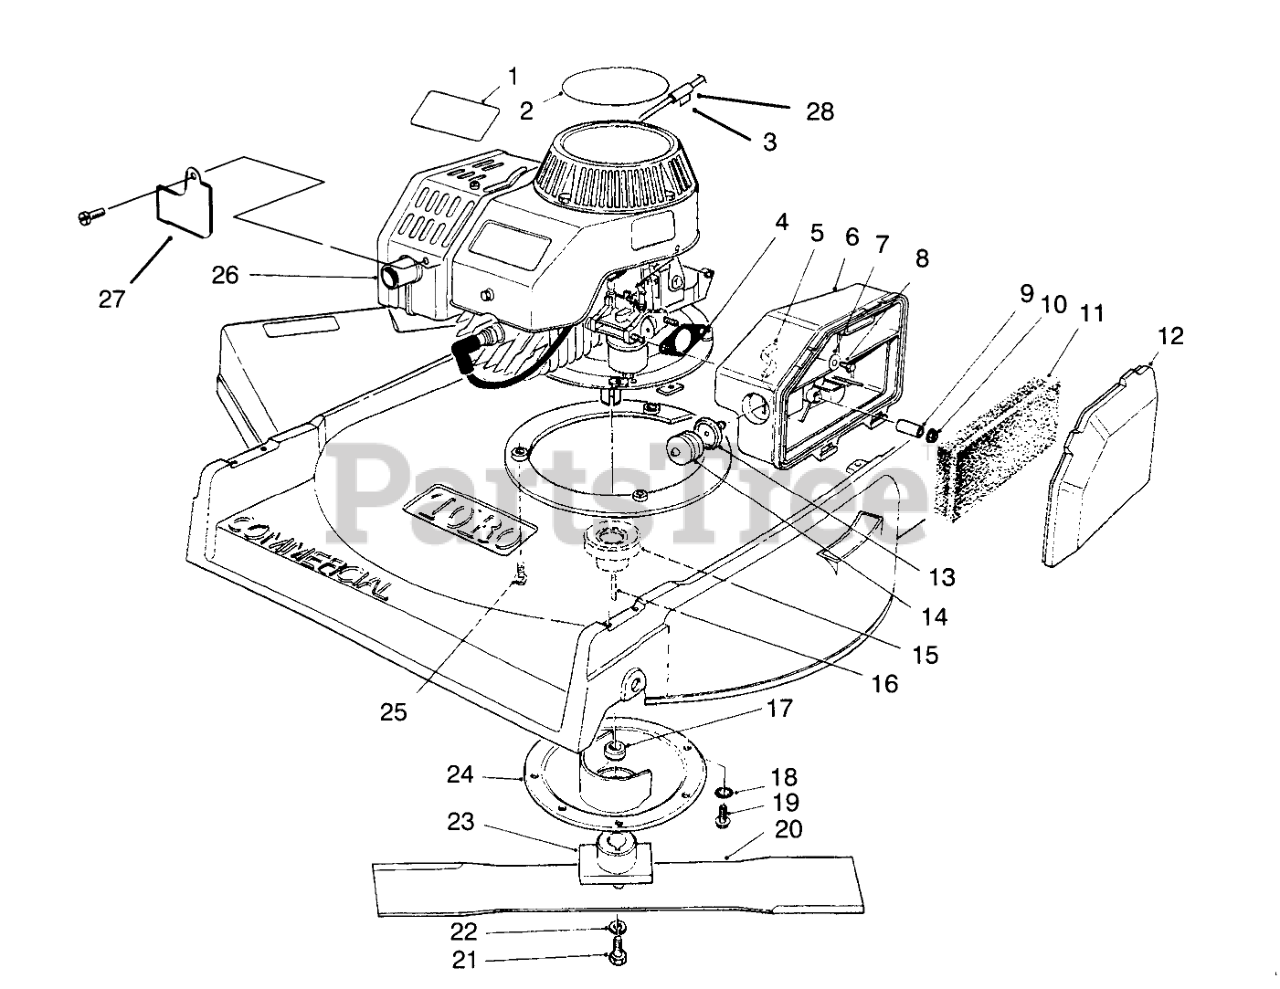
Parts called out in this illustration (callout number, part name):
1	DECAL - PROLINE
2	DECAL-2 CYC RECOIL COMM
3	Staple
4	GASKET-AIR CLEANER
5	HOSE-PRIMER
6	BODY-AIR CLEANER
7	WASHER-FLAT
8	SCREW-HH
9	SPACER
11	ELEMENT-AIR CLEANER
12	COVER-AIR CLEANER
13	BODY-PRIMER
14	BULB-PRIMER
15	PULLEY-DRIVER
16	KEY-SQUARE
17	BLADE SPACER
18	WASHER-LOCK, INTERNAL
19	SCREW-HWHTF
20	BLADE
21	SCREW-BLADE
22	WASHER-LOCK
23	BLADE RETAINER WA
24	PROTECTOR-CRANKSHAFT
25	SCREW-HHF
26	ENGINE ASM
27	EXTENSION-MUFFLER GUARD
